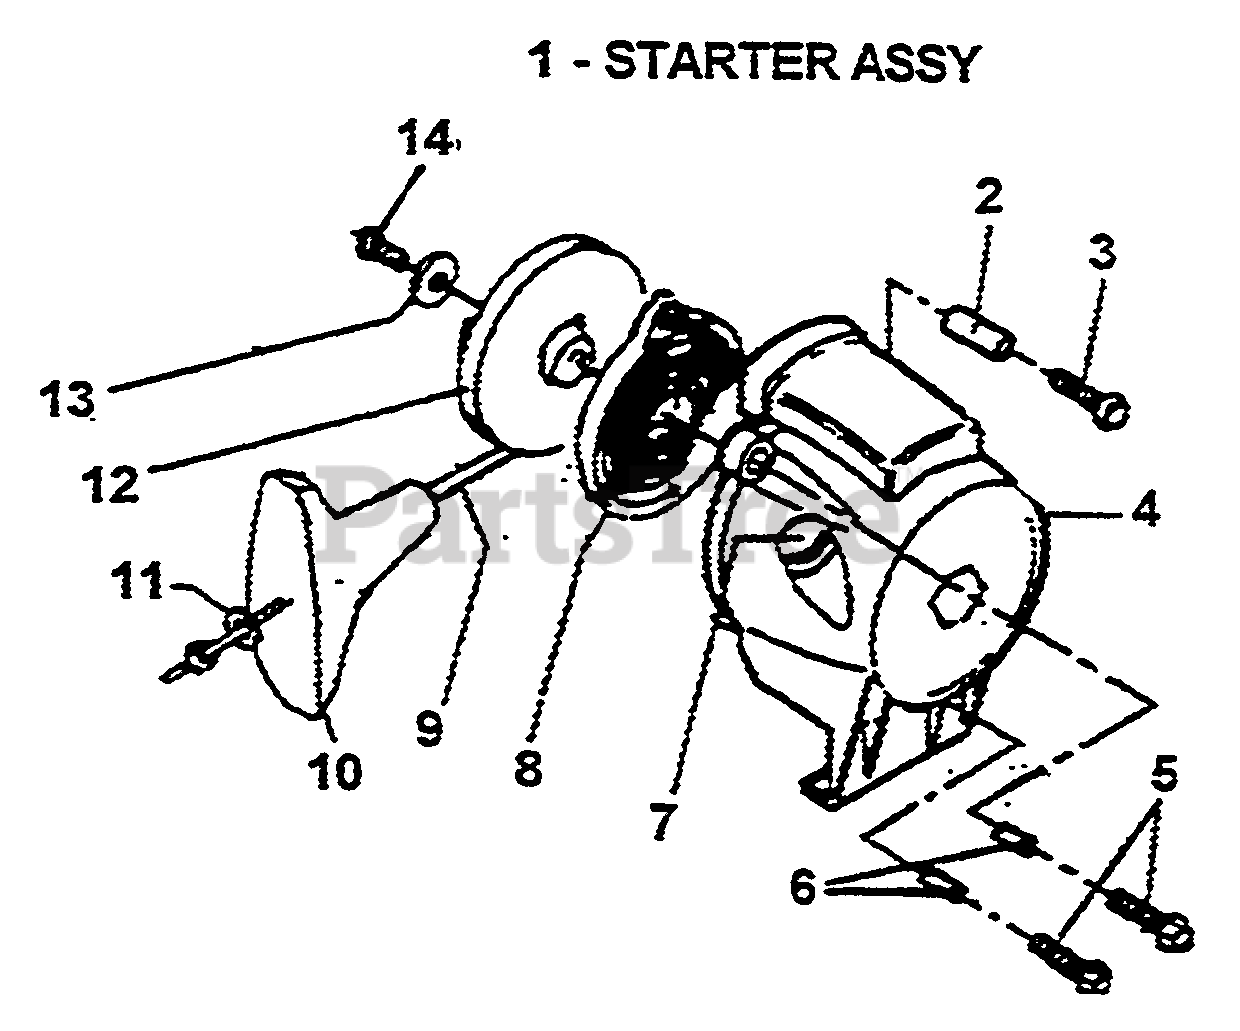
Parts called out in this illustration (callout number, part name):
1	STARTER ASSY
4	HOUSING, STARTER
7	GUIDE, ROPE
12	ROPE & DRUM ASSY
